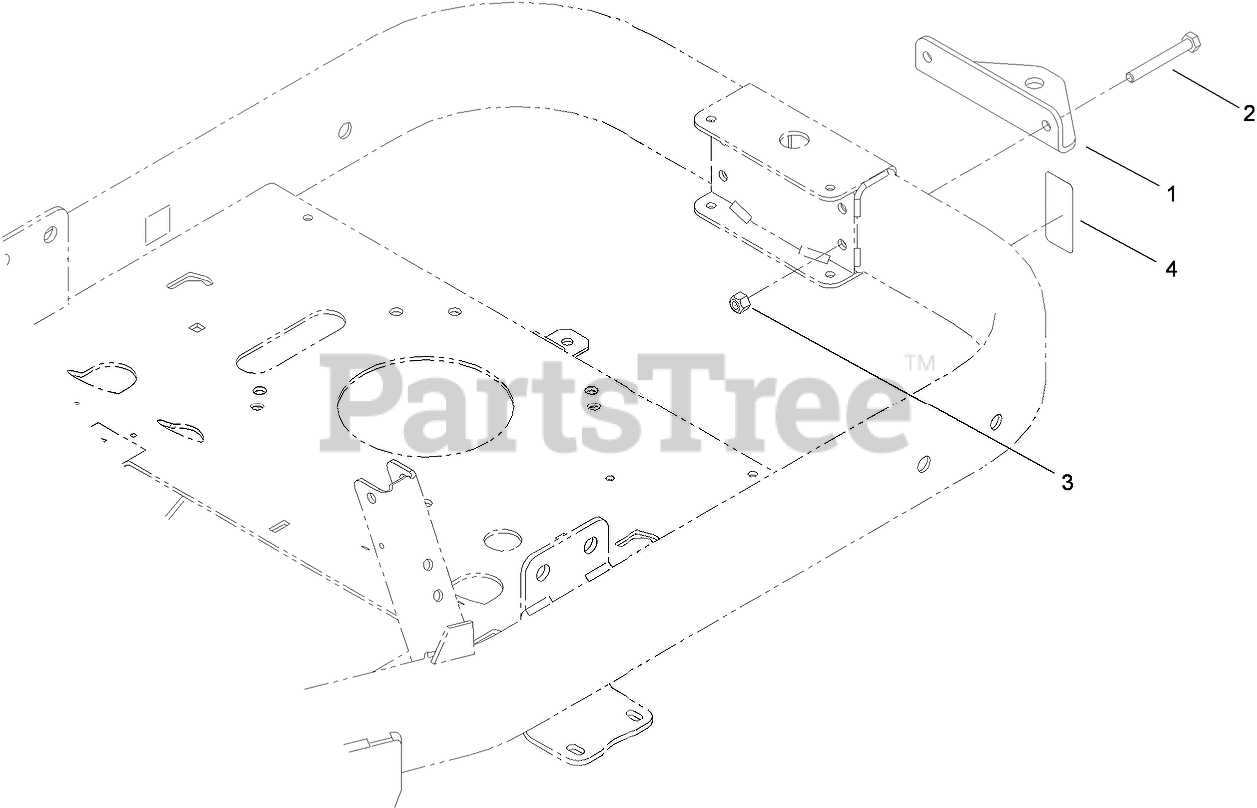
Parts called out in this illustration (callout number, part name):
1	BRACKET-HITCH
2	SCREW-HH
3	NUT-LOCK, NI
